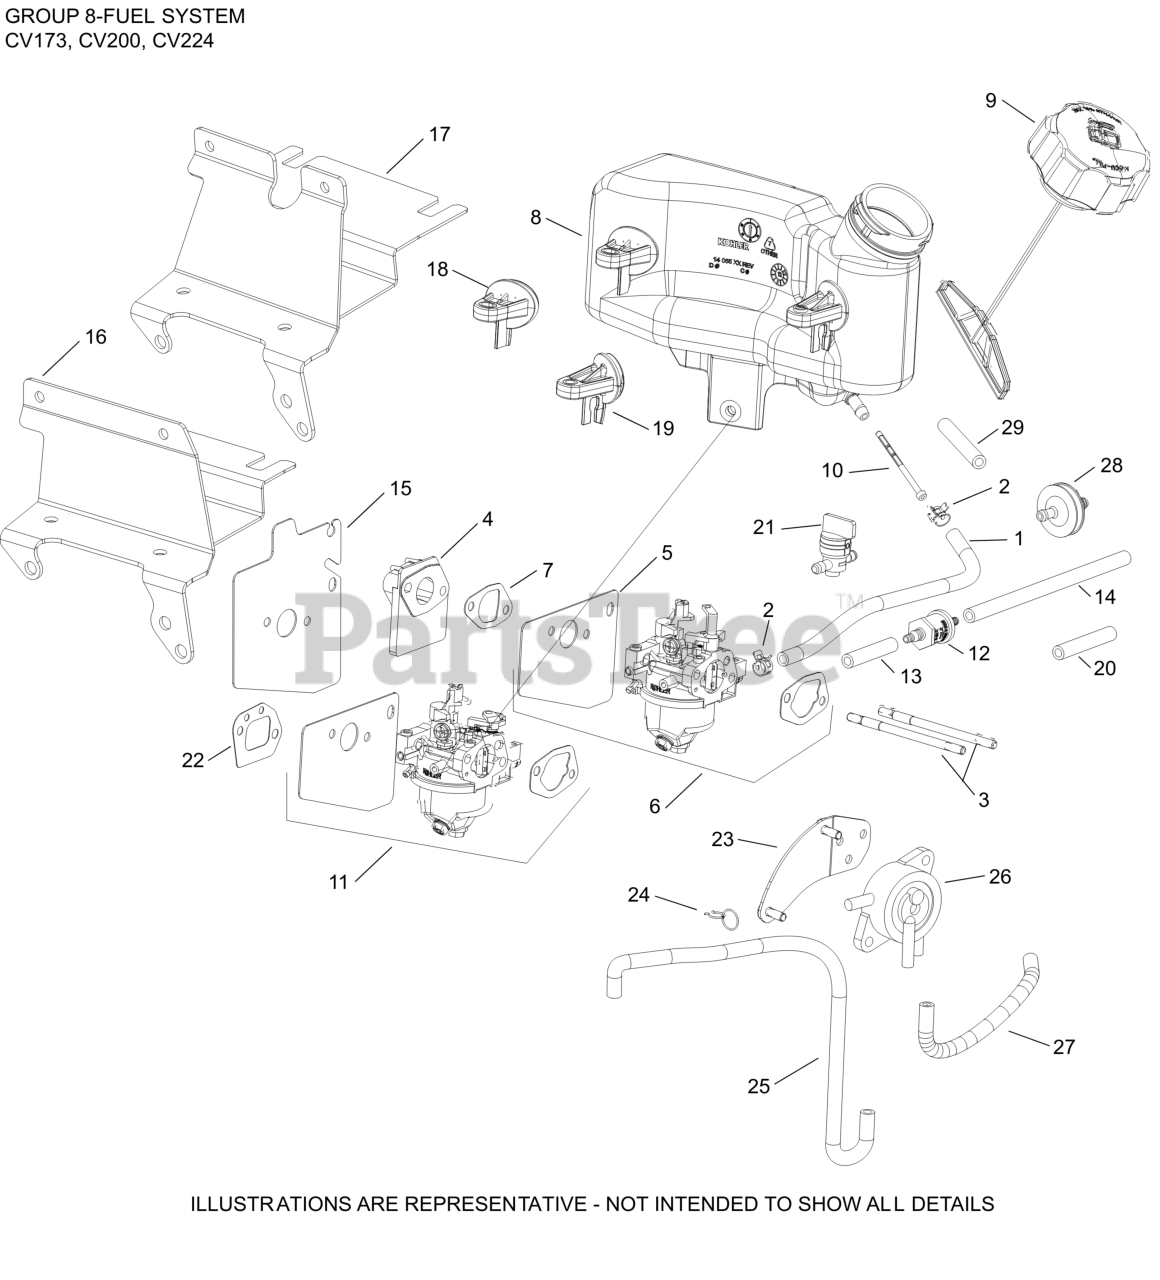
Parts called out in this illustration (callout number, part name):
2	CLAMP, HOSE (NON-CALIF)(#1423710S)
3	STUD,M6X1.0X100.2MM
4	KIT, SPACER
5	KIT, CARBURETOR HEAT SHIELD GASKET
7	KIT, INTAKE GASKET
11	KIT, CARBURETOR COMPLETE
13	HOSE, FUEL LOW-PERMEATION
14	HOSE, FUEL LOW-PERMEATION
22	GASKET SPACER
28	FILTER, FUEL
NI	KIT,HIGH AL(4000-8000 FT)USE 14 755 04-S
NI	KIT, CARBURETOR REPAIR (RUIXING)
